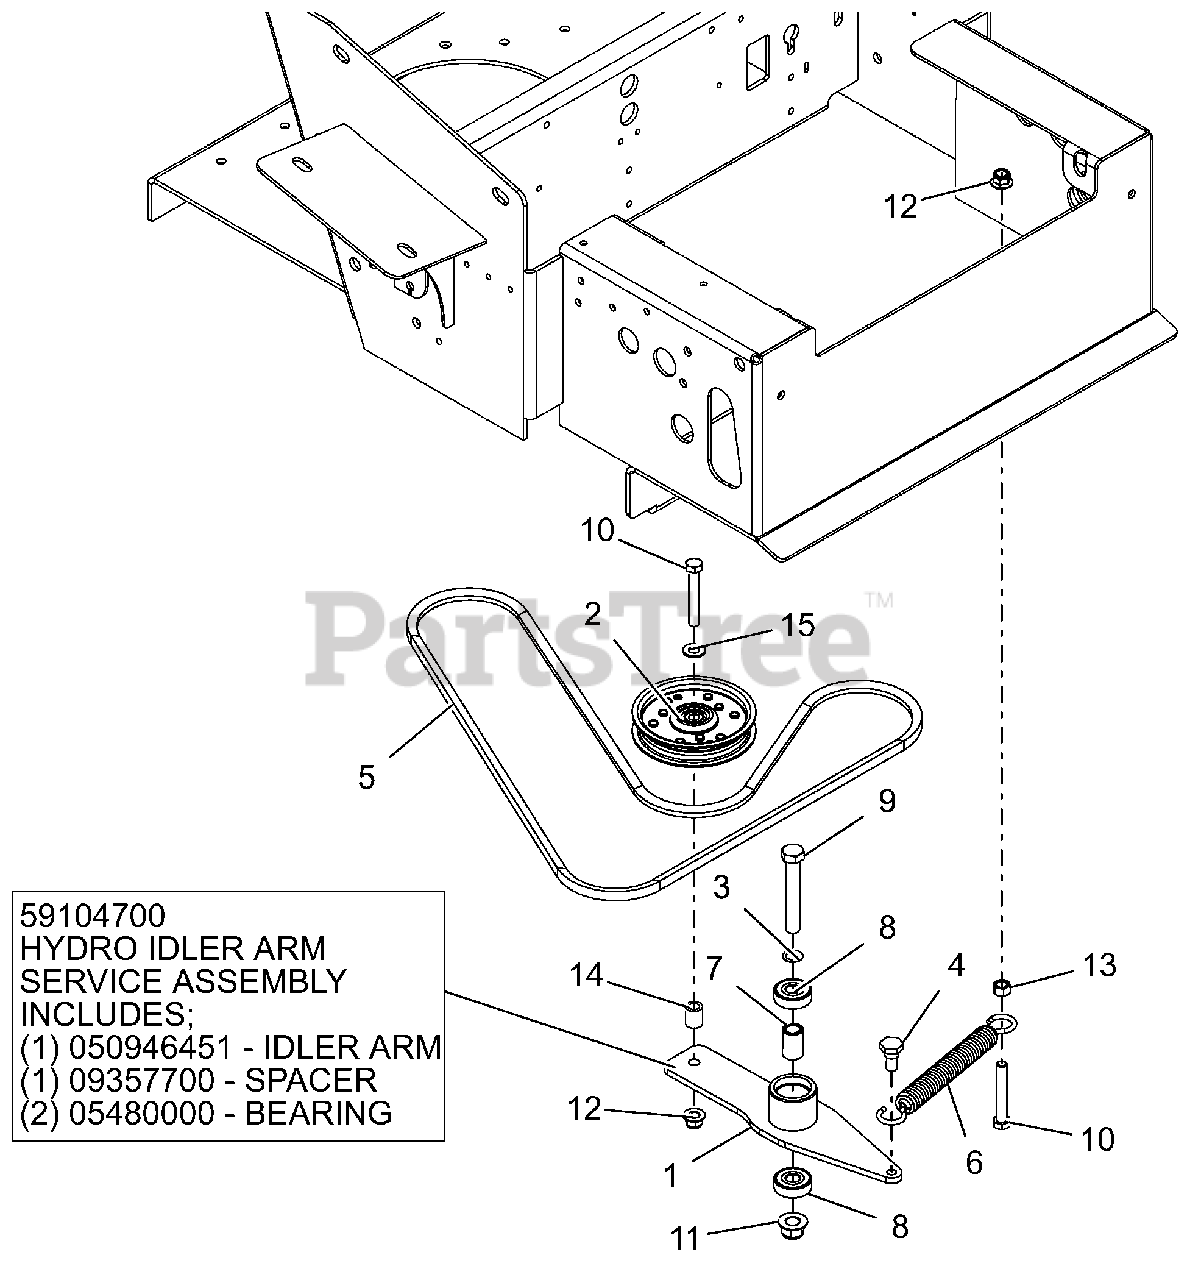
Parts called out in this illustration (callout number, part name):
1	HYDRO DRIVE IDLER ARM WMT-BLK
1	HYDRO IDLER ARM ASSEMBLY
2	ASM, 4" IDLER (.75 WIDE)
3	WASHER, .500X.750X.020 THRUST
4	BLT,SHLDR EP .38-16X.30 HEX YZ
5	V-BELT, A-COGGED
6	SPRING, EXTENSION
7	SPACER .510 X .75 X 1.1485
8	BRG-BALL .500X1.38X.437
9	@BLT-HEX .50-13X3.25 GR5 YWZC
10	@BLT-HEX .38-16X2.50 GR5 YWZC
11	@NUT-LK-NYL-FLG .50-13 YWZC
12	@NUT-LK-NYL-FLG .38-16 YWZC
13	@NUT-HEX .38-16 YWZC
14	BSHG-SLV .407X.625X.750 PL
15	@WSHR-FL-STL.406X.812X.065 YWZ
